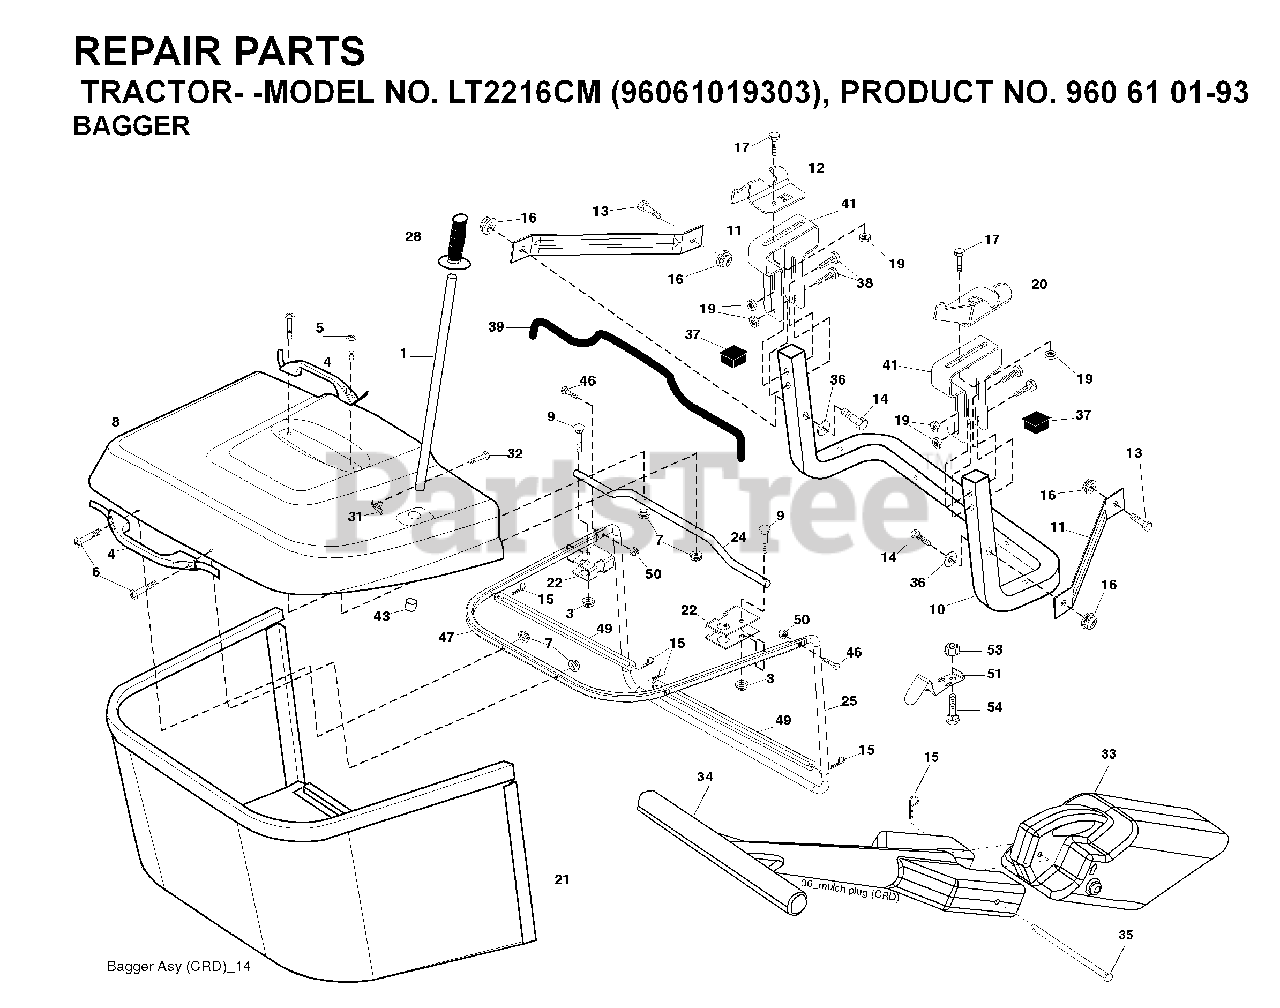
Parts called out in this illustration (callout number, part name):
1	TUBE HANDLE
3	NUT T
5	SCREW.PAN.HEAD
11	BRACKET
14	BOLT-HEX EAK
15	RETAINER-SPRNG RB
16	NUT LOCK FLG 3/8-16 UNC
17	BOLT
19	NUT LOCK HEX FLANGE 5/16-18
20	BRKT.PIVOT.RH.CRD
21	BAGGER.ASM.CRD.2007
22	BRACKET
24	TUBE
28	GRIP.HANDLE.BLACK
31	RETAINER CLIP
32	RIVET,DRILLED
33	PLUG
35	PIN
38	BOLT.5/16-18X2.5
39	SEAL.BAGGER.CRD
41	BRKT, BAGGER
43	PLUG, TUBING END
46	BOLT.CARRIAGE.5/16-18
50	NUT.71038.31-18.HEX.NYLOCK
53	NUT
54	BOLT
